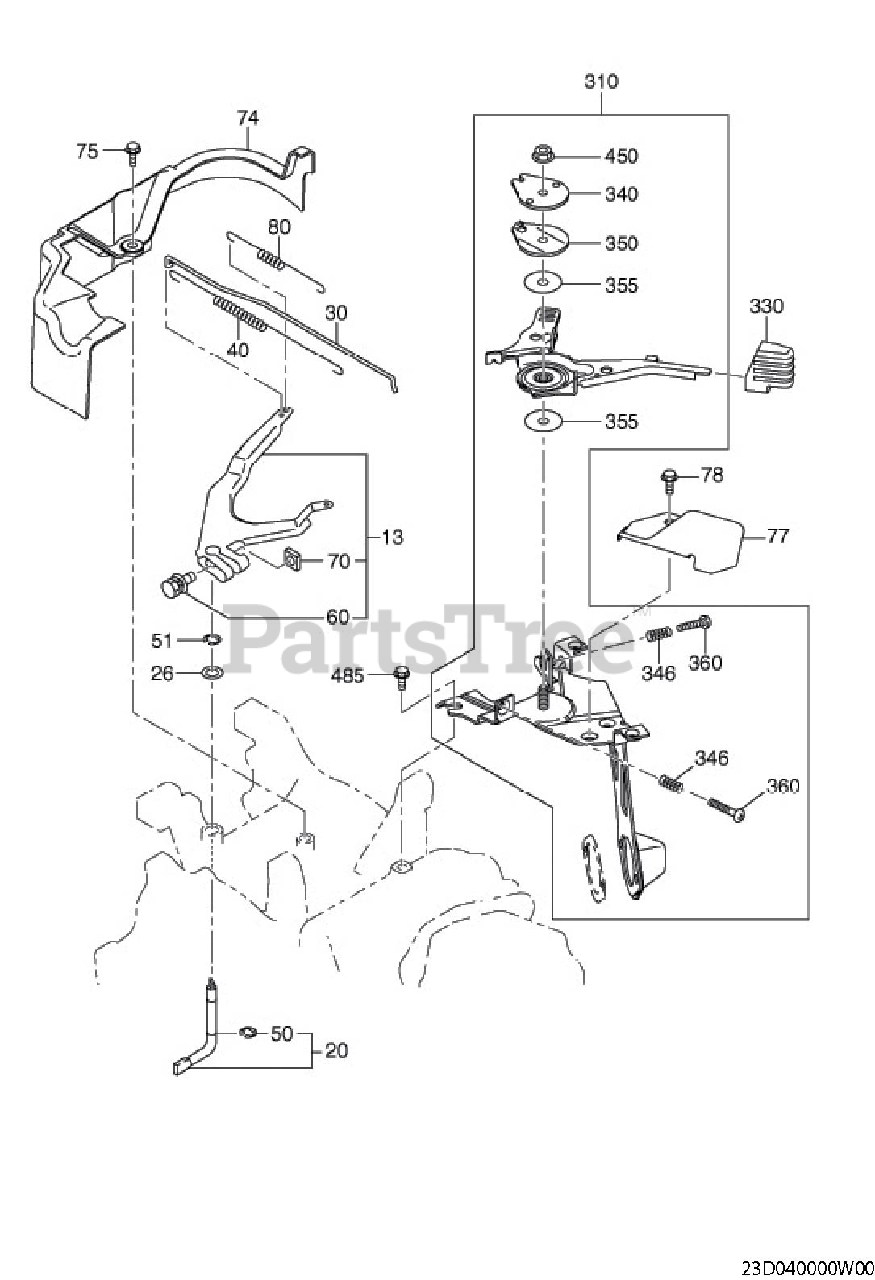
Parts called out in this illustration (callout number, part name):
13	GOVERNOR LEVER AY
20	GOVERNOR SHAFT CP
26	WASHER
30	GOVERNOR ROD
50	CLIP
51	CLIP
60	BOLT AND WASHER AY
70	NUT
74	COVER(GOVERNOR) CP
75	FLANGE BOLT
77	BAFFLE 5 CP
78	FLANGE BOLT
80	GOVERNOR SPRING
310	SPEED CONTROL AY
330	KNOB(SPEED CONTROL LEVER)
346	SPRING (ADJUST)
350	SPRING WASHER
355	FRICTION WASHER
360	SCREW
450	SELF LOCK NUT
485	FLANGE BOLT
